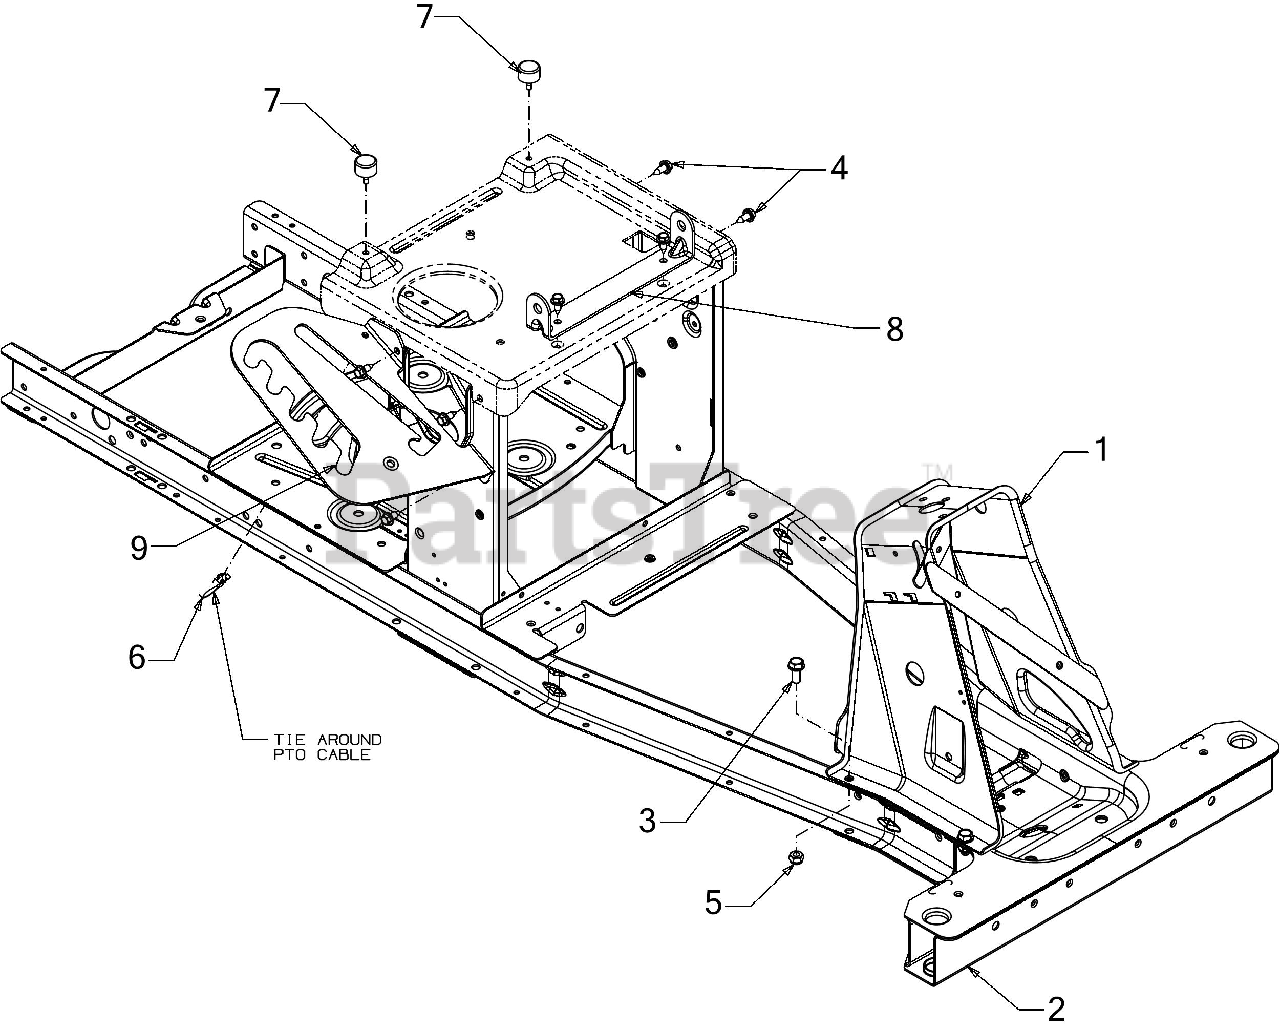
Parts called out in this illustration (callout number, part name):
1	STEER PEDESTAL ASSEMBLY
2	FRAME ASSEMBLY
3	SCREW 5/16-18 x .750 GR8
4	SCREW 1/4-20X.625
5	HEX NUT
6	PUSH MOUNT TIE
7	BUMPER .62 DIA x .50
8	PIVOT SEAT BRACKET
9	DECK LIFT BRACKET
